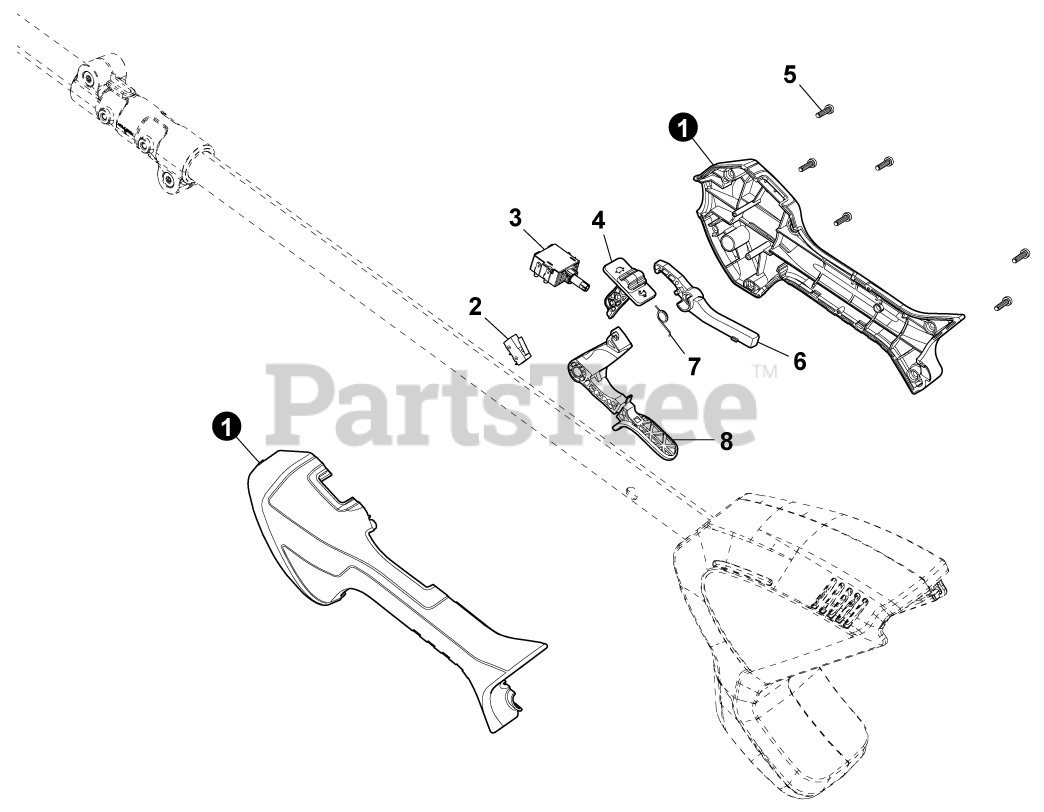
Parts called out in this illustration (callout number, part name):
1	HANDLE ASSY
2	SWITCH, MICRO
3	SWITCH, SPEED CONTROL
4	KNOB, SWITCH
6	LEVER, INTERLOCK
7	SPRING, TORSION
